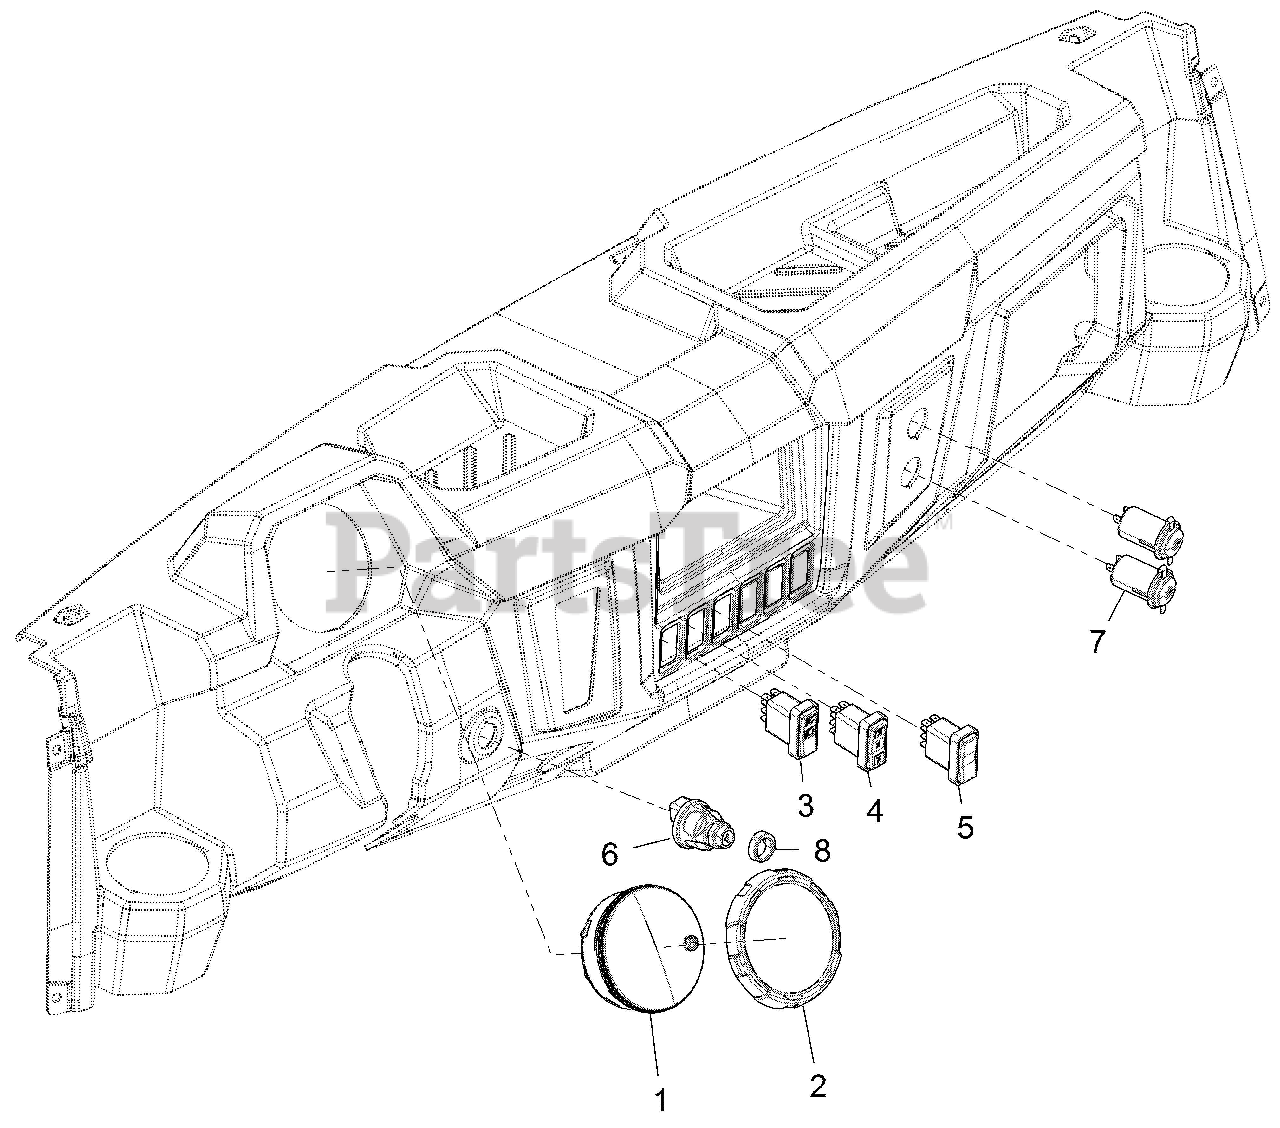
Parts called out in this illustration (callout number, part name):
1	ASM-CLSTR,CPIA3,OSPS,ESIN
2	MOUNT-RUBBER,INSTR. CLUSTER
3	SWITCH-HEADLIGHT
4	SWITCH-AWD
5	SWITCH-BOX LIFT,MOMENTARY
6	SWITCH,KEY,ARIENS
7	RECEPTACLE-POD MNT,12 VOLT
8	SPACER, KEY, SWITCH
